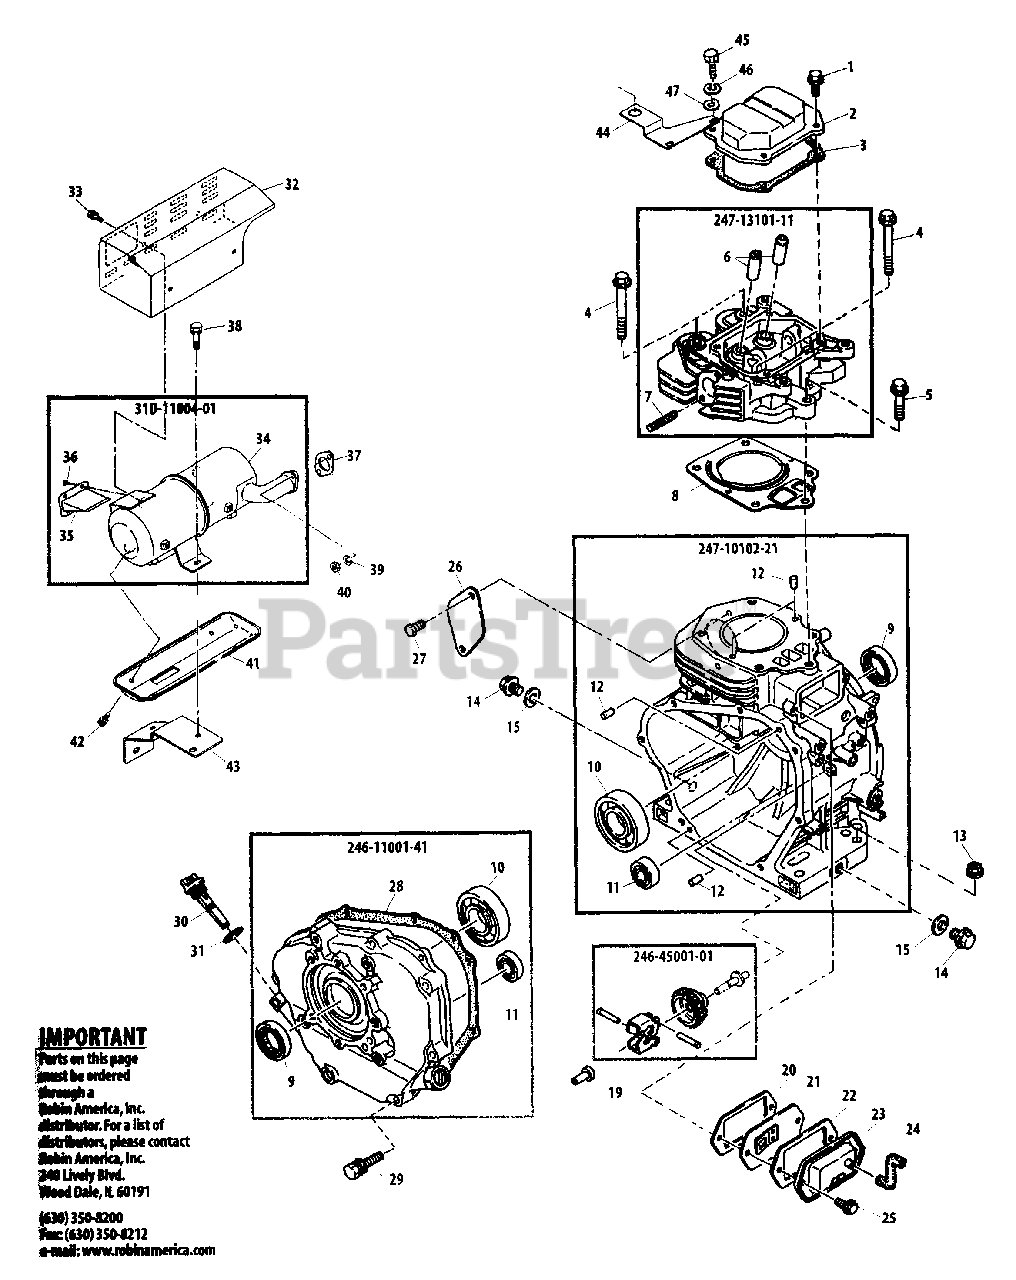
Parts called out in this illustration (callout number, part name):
1	BOLT
2	ROCKER COVER
3	GASKET
4	BOLT
5	BOLT
6	GUIDE, VALVE
7	STUD
8	GASKET, HEAD
9	SEAL, OIL
10	BEARING, BALL
11	BEARING, BALL
12	DOWEL PIN
13	NUT - FLANGE
14	PLUG
15	GASKET
19	GOVERNER SLEEVE
20	GASKET
21	PLATE
22	GASKET
23	COVER, BREATHER
24	TUBE
25	BOLT - FLANGE
26	COVER
27	BOLT
28	GASKET
29	BOLT
30	OIL GAUGE
31	GASKET
31D-11004-01	MUFFLER ASSY
32	MUFFLER COVER - UPPER
35	SCREEN, SPARK ARRESTER
39	WASHER, SPRING 8
41	MUFFLER COVER - LOWER
44	STOPPER STAY
46	WASHER, SPRING 10
246-11001-41	MAIN BEARING COVER ASSY
246-45001-01	GOVERNOR GEAR ASSY
247-10102-21	CRANKCASE ASSY
247-13101-11	CYLINDER HEAD ASSY
